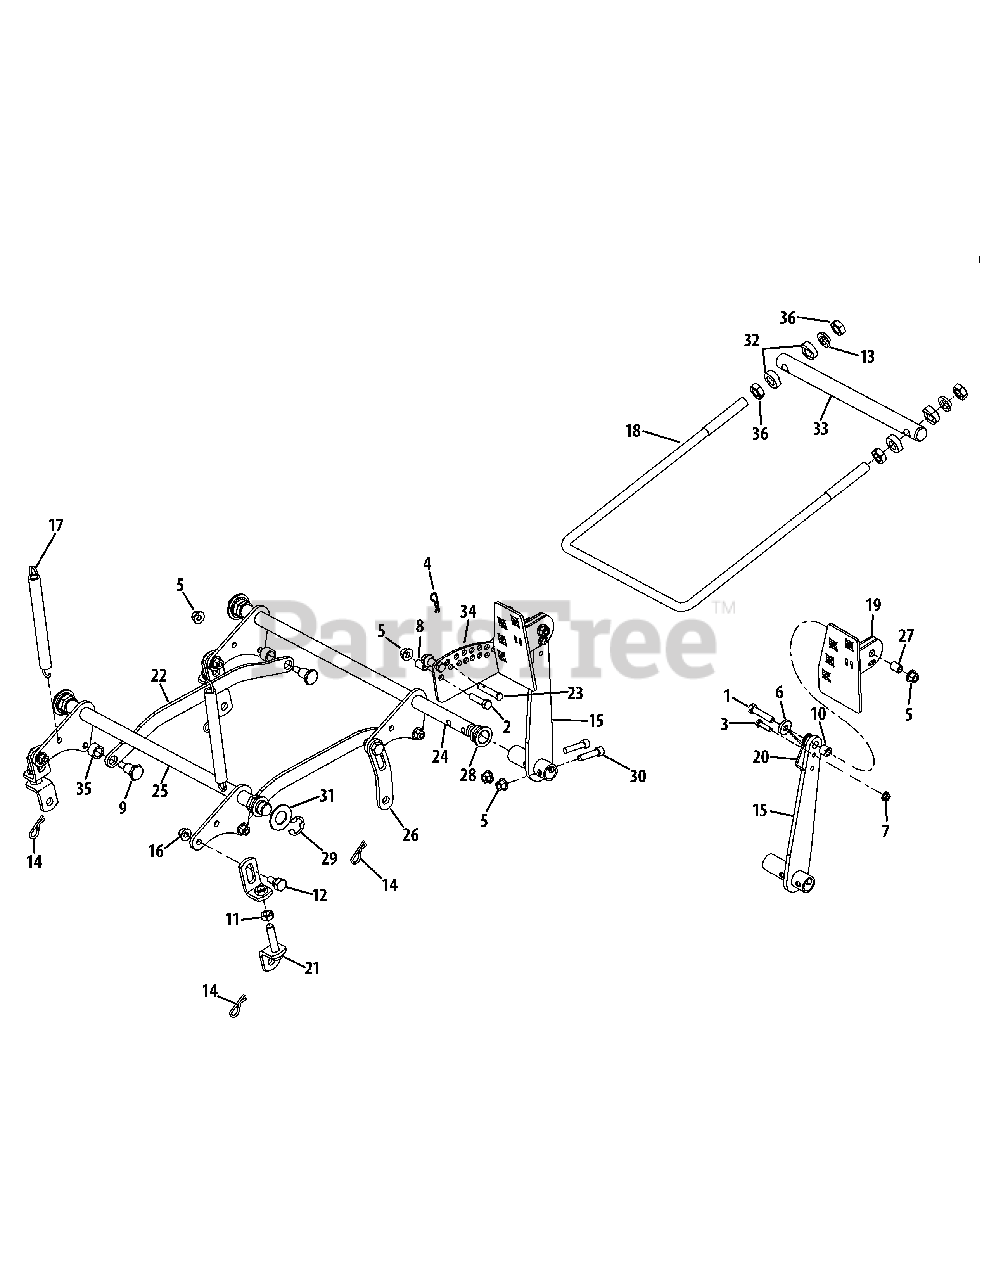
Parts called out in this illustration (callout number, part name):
1	Hex Screw, 3/8-16 x 1.75
2	Hex Screw, 3/8-16 x 1.50
3	Hex Screw, 1/4-20 x 1.00
4	Hair Pin, 3/8 x 1.562 x .080
5	Flange Counterlock Nut, 3/8-16
6	Washer, .390 x 1.00 x .180
7	Flange Toplock Nut, 1/4-20
8	Spacer, .375 x .500 x .750
9	Shoulder Bolt, 3/8-16 x .625 x .830
10	Spacer, .385 x .625 x .500
11	Jam Nut, 1/2-20
12	Shoulder Bolt, 3/8-16 x .56 x .27
13	Lock Washer, .633 x 1.07 x .161
14	Hair Pin, 1/2 x 1.625 x .125
16	Adjustable Deck Lift Bracket
17	Extension Spring, .75 x 7.89 x .14
18	Front Lift Rod
19	Foot Pedal Assembly
20	Torsion Spring, .900 x 2.3 x .09
21	Lower Bracket Assembly
22	Lift Connecting Link
23	Clevis Pin, 3/8 x 2.05
24	Front Shaft Assembly
25	Rear Shaft Assembly
26	Curved Link Plate
27	Spacer, .380 x .500 x .667
28	Hex Flange Bearing, 7/8
29	Retaining Clip, .675
30	Sockt Cap Screw, 3/8-16 x 1.50
31	Washer, .940 x 1.75 x .110
32	Spacer, .635 x 1.2 x .41
33	Trailing Link Pivot Rod
35	Spacer, 632 x .877 x .548
36	Jam Nut, 5/8-11
